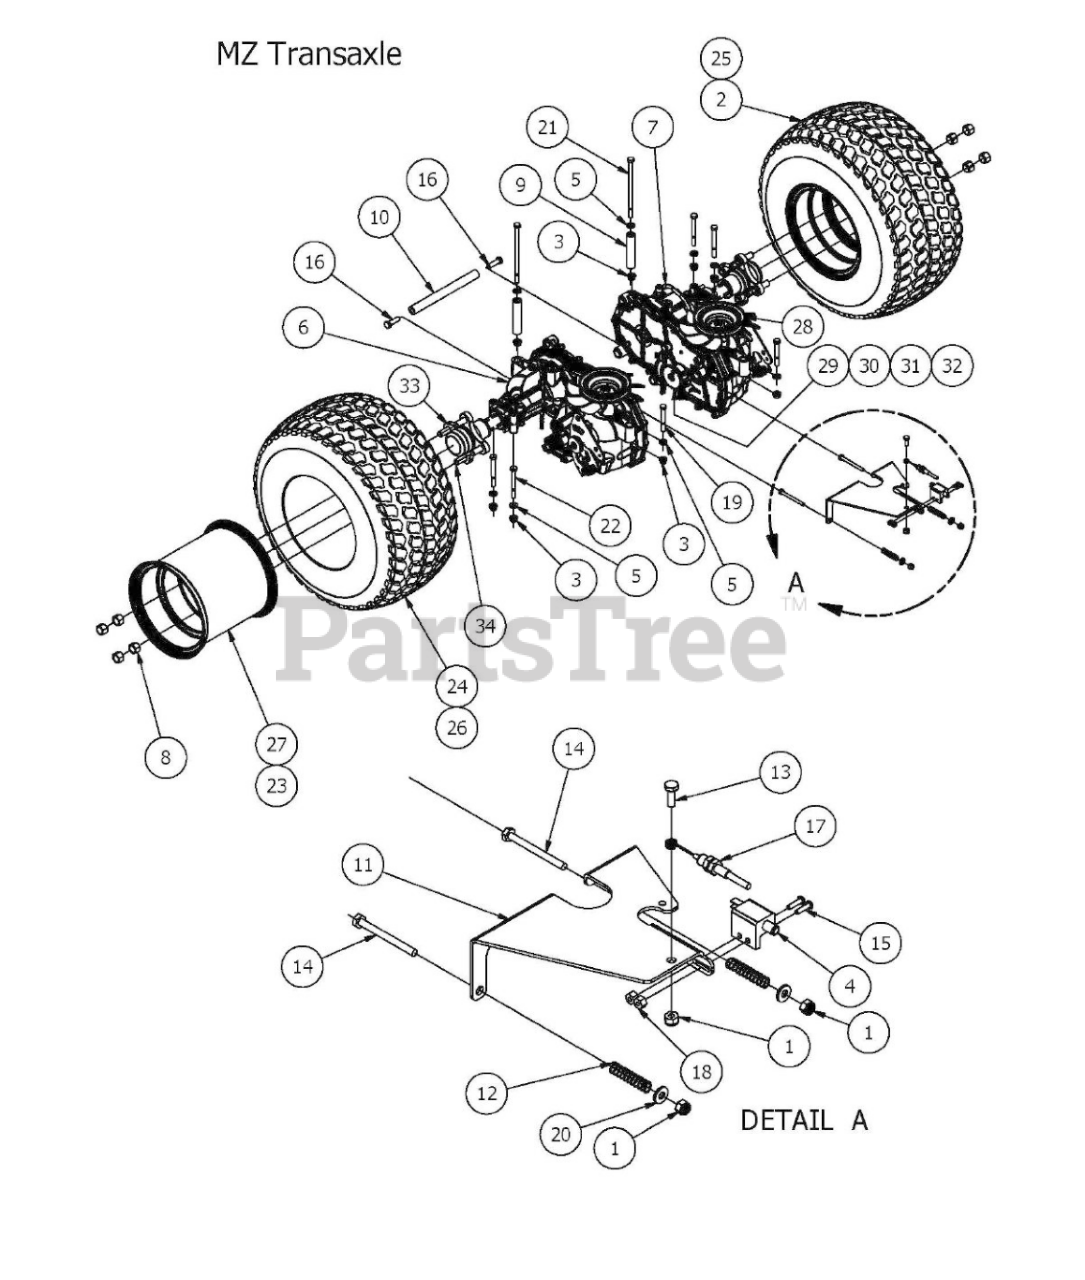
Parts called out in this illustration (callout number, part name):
1	1/4 Nylock Nut
2	18x9.50-8 48 and 54 mz only
3	5/16" Nylon Flange Nut
4	Safety Switch
5	5/16" Flat Washer
6	2017 MZ Right Transaxle
7	2017 MZ Left Transaxle
8	Acorn Lug Nut
9	2017 Transaxle Spacer
10	2017 Transaxle Spacer-MZ
11	2017 MZ Brake Lock Bracket
12	Brake Spring
13	1/4" x 3/4" Hex Bolt
14	1/4-20 x2-1/2 Gr2 hex C/s zinc
15	10-24 X 5/8 Button Head Bolt
16	3/8" x2" Hex Bolt
17	2017 MZ Brake Cable
18	10-24 Nylon Insert Locknut
19	5/16 x 2 1/2 Bolt
20	1/4" Flat Washer
21	5/16" x 6" Bolt
22	5/16" x 3" Hex Bolt
23	42 MZ Wheel
24	42 MZ Tire
25	42 MZ Wheel & Tire Assembly 18x8.50-8
26	48 & 54 MZ Tire
27	48 & 54 MZ Wheel
28	MZ Fan & Pully Kit
29	MZ Brake Cog Kit
30	MZ Retainer Ring for Brake
31	MZ Brake Gear
32	MZ Brake Arm Kit
33	MZ Hub Kit
34	Transaxle Wheel Studs
